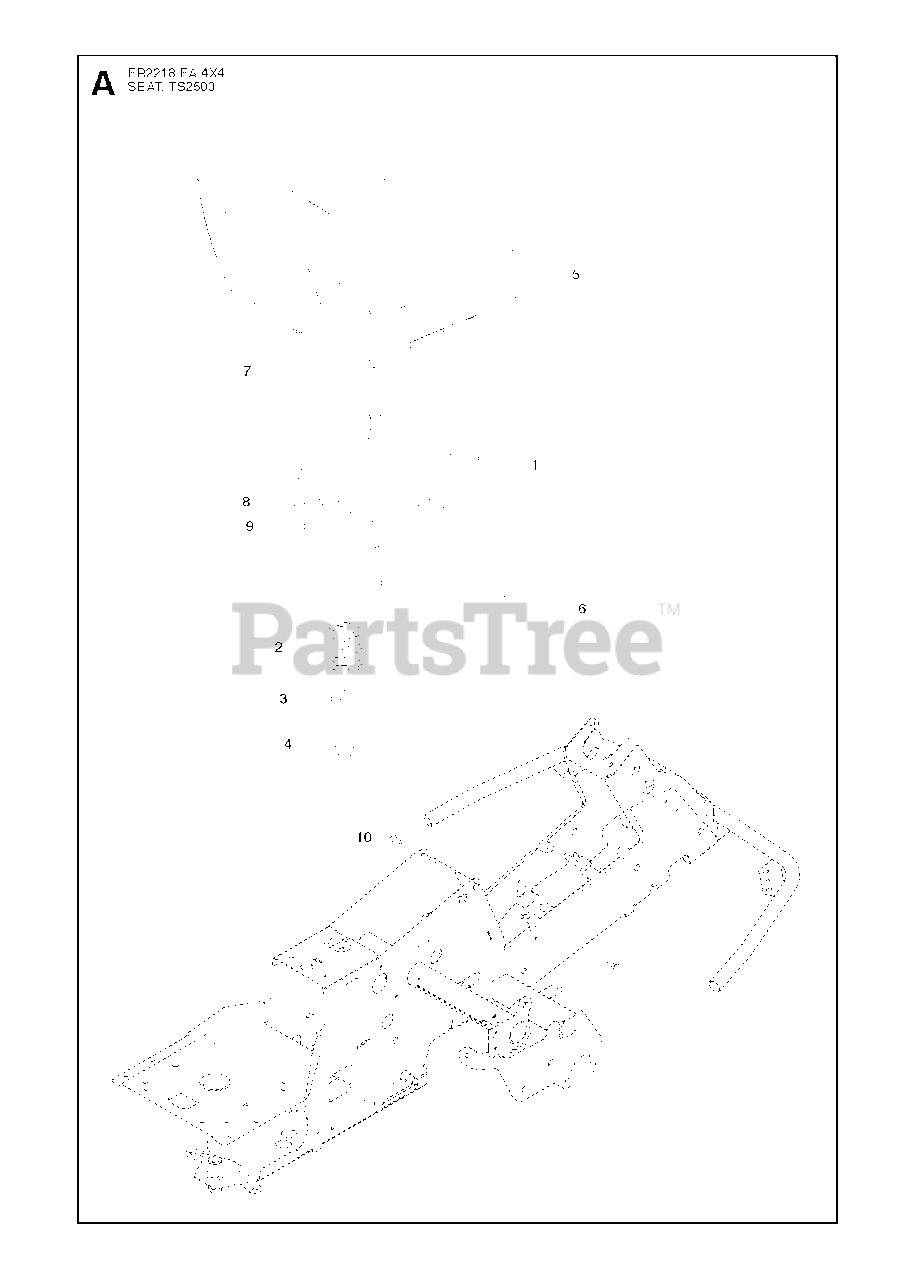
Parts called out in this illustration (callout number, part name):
2	SEAT SPRING
4	SCREW M10X25
6	ADJUSTING KNOB
